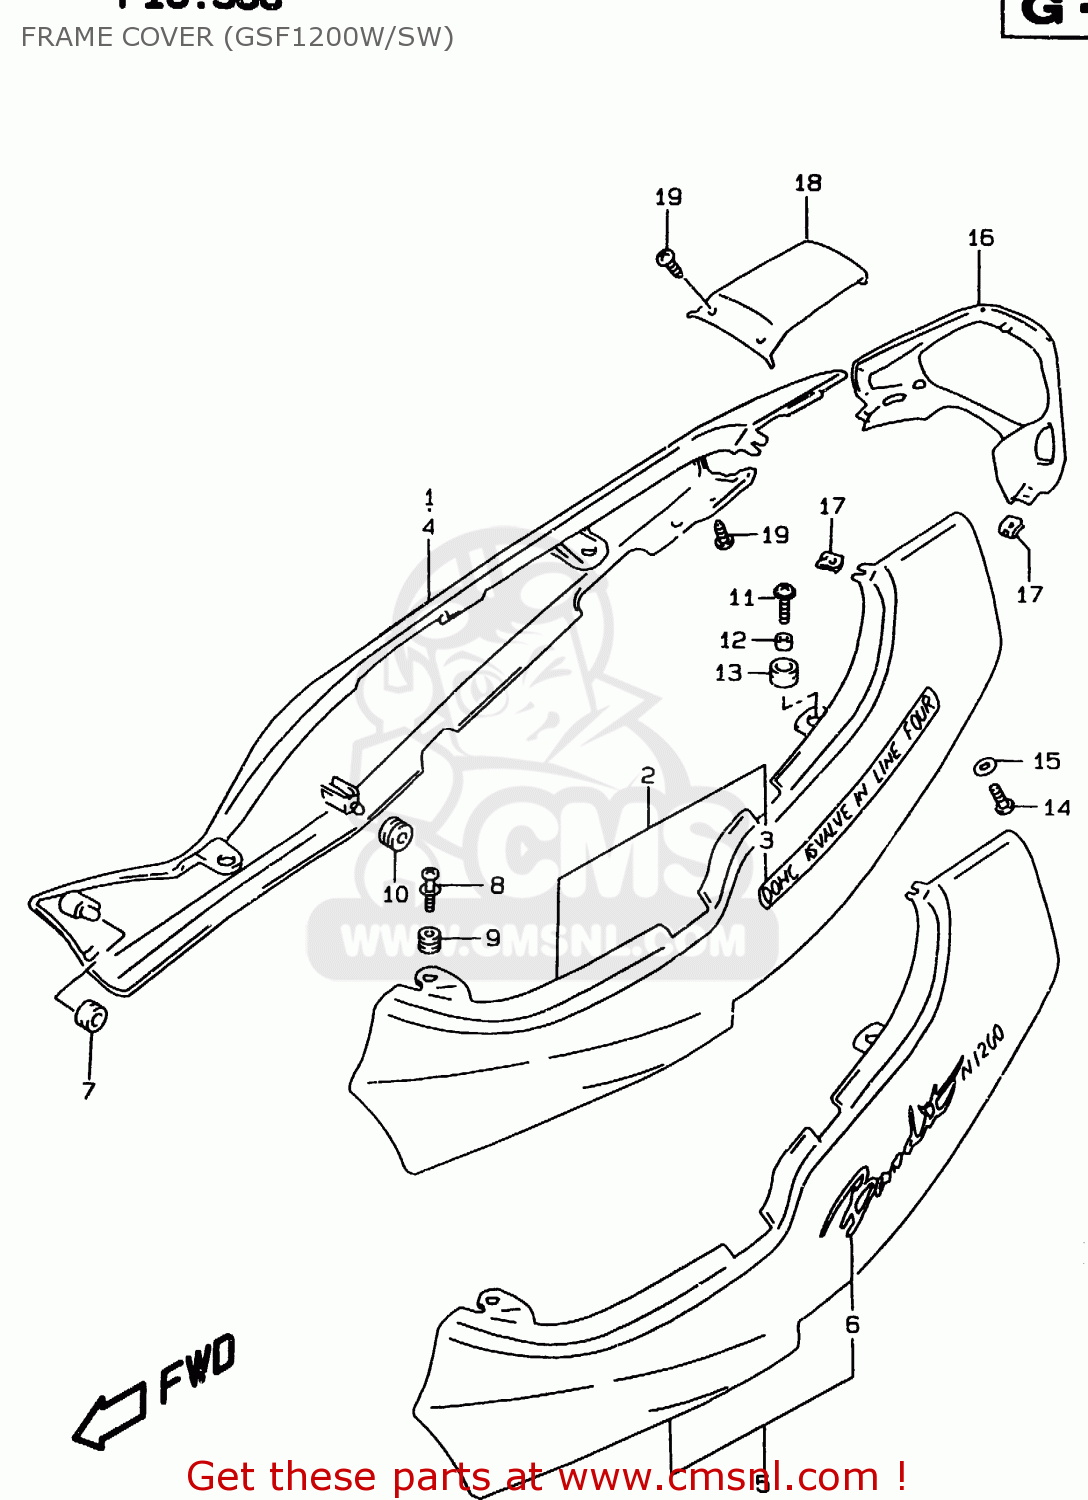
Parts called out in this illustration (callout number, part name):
1	COVER,FRAME,R(BLACK)
2	COVER,FRAME,L(BLACK)
3	EMBLEM,FRAME COVER
4	COVER,FRAME,R(BLACK)
5	COVER,FRAME,L(BLACK)
6	EMBLEM,FRAME COVER
7	CUSHION,FRAME COVER FR
8	CLIP
9	CUSHION
10	CUSHION
11	SCREW(6X20)
12	SPACER(6.5X10X9.4)
13	CUSHION
14	SCREW
15	WASHER(6.3X16X1.5)
16	COVER,FRAME RR
17	NUT
18	COVER,FRAME CTR
19	SCREW
